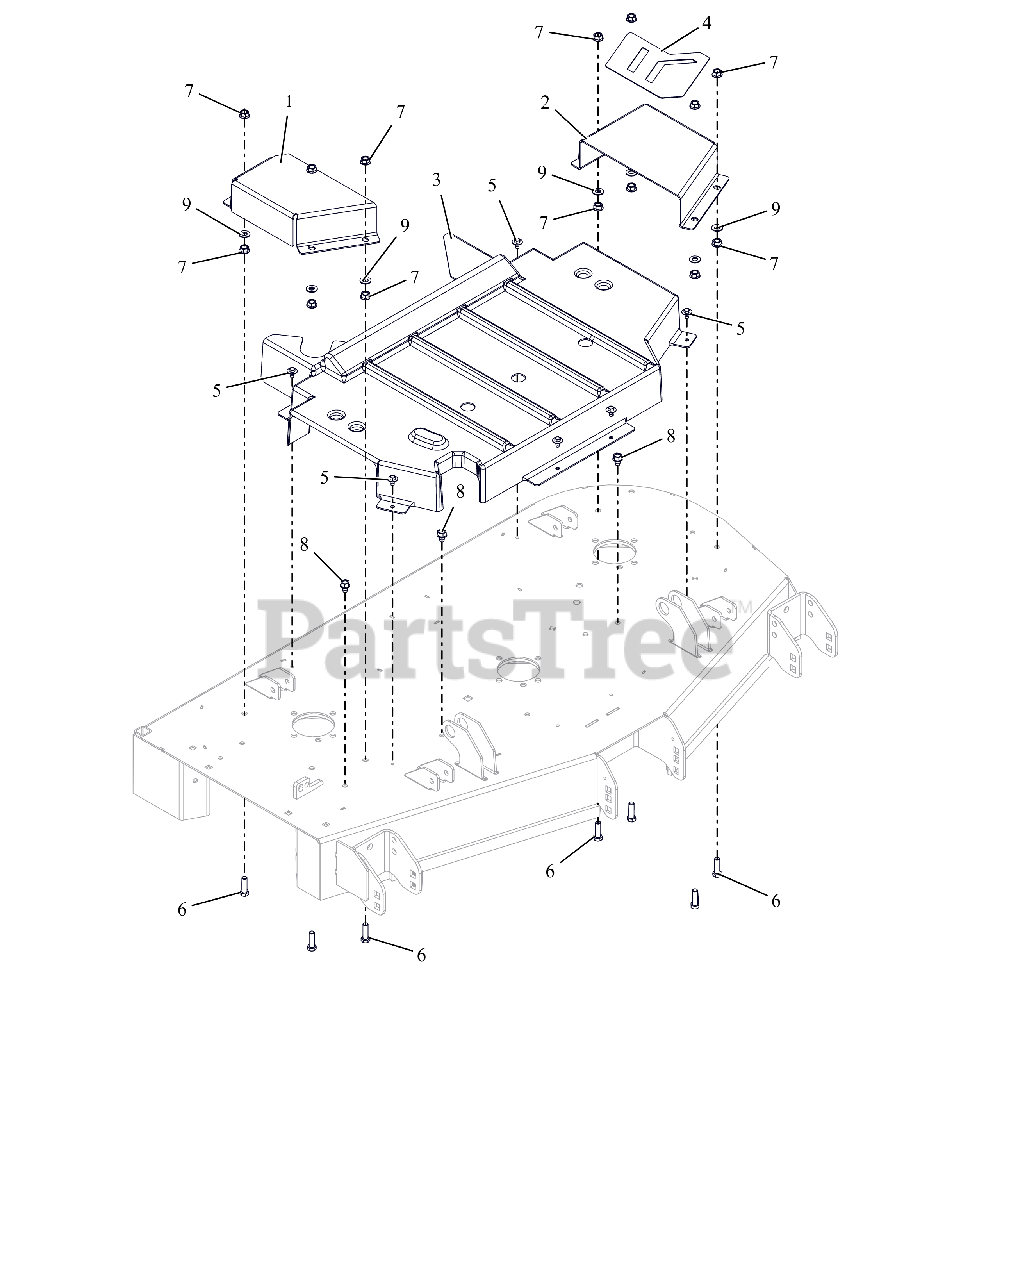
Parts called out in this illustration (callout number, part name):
1	GUARD BELT, 48" RIGHT CE
2	GUARD BELT 48" LEFT CE
3	GUARD, CENTER DECK SPINDLE CE
4	GRIP TAPE 48 BELT COVER
5	SCR-TAP .25-20X.50 LGHWH TR YZ
6	@BLT-HEX .38-16X1.25 GR5 YWZC
7	@NUT-SPNLK-FLG .375-16 YWZC
8	@SCR-TAP .38-16X.50 HWH TR YWZ
9	@WSHR-FL-STL.406X.812X.065 YWZ
